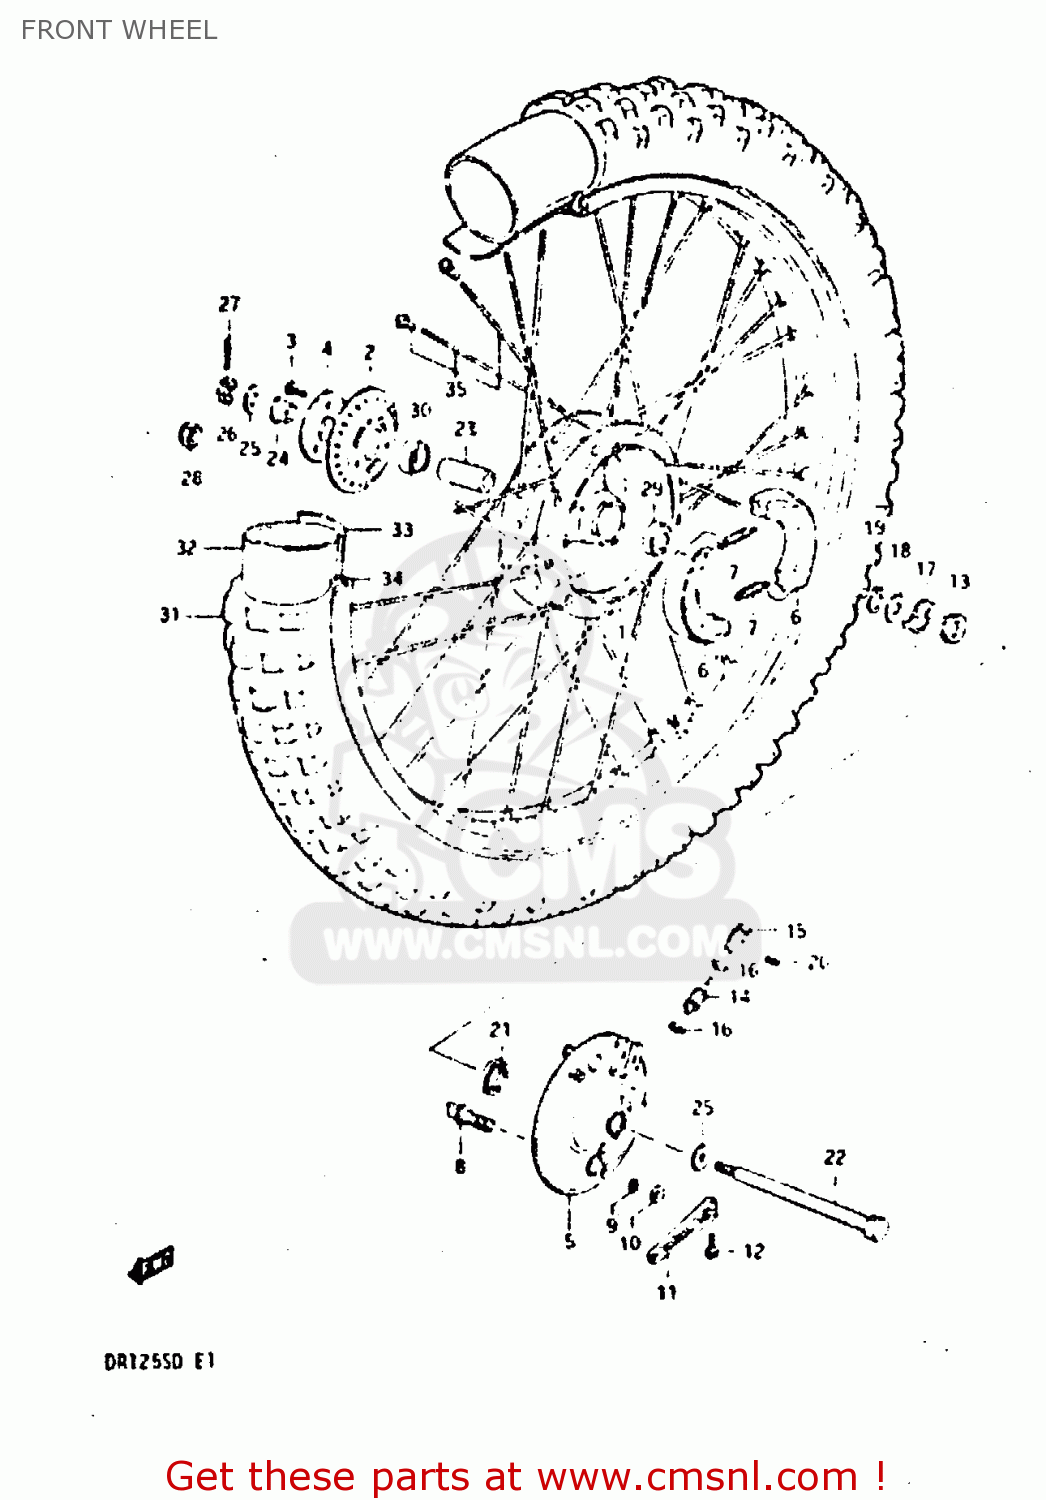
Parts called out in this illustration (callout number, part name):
1	HUB,FR WHEEL
2	FLANGE,FR HUB,R
3	BOLT
4	PLATE,FRONT HUB BEARING
5	PANEL,FRONT HUB
6	SHOE,BRAKE
7	SPRING(L:34)
8	CAM,FRONT BRAKE
9	O-RING (D:2.4 ID:13.8)
10	WASHER (14.5X22X1.6)
11	LEVER,FRONT BRAKE CAM
12	BOLT
13	GEAR,SPEEDOMETER
14	PINION,SPEEDOMETER
15	BUSH,METER GEAR OUTER
16	WASHER (5.1X9X0.4)
17	DRIVER,SPEEDOMETER GEAR
18	WASHER(18.5X24X1)
19	CIRCLIP
20	SCREW
21	OIL SEAL (43X58X7)
22	AXLE,FRONT
23	SPACER (12.6X19X52)
24	SPACER,FR AXLE,R
25	WASHER
26	NUT 12MM
27	COTTER PIN
29	BEARING
30	BEARING, RH
31	TIRE,FRONT
32	TUBE
33	PROTECTOR,WHEEL,INNER
34	RIM, WHEEL (1.60*21)
35	SPOKE ASSY,FR WHEEL
